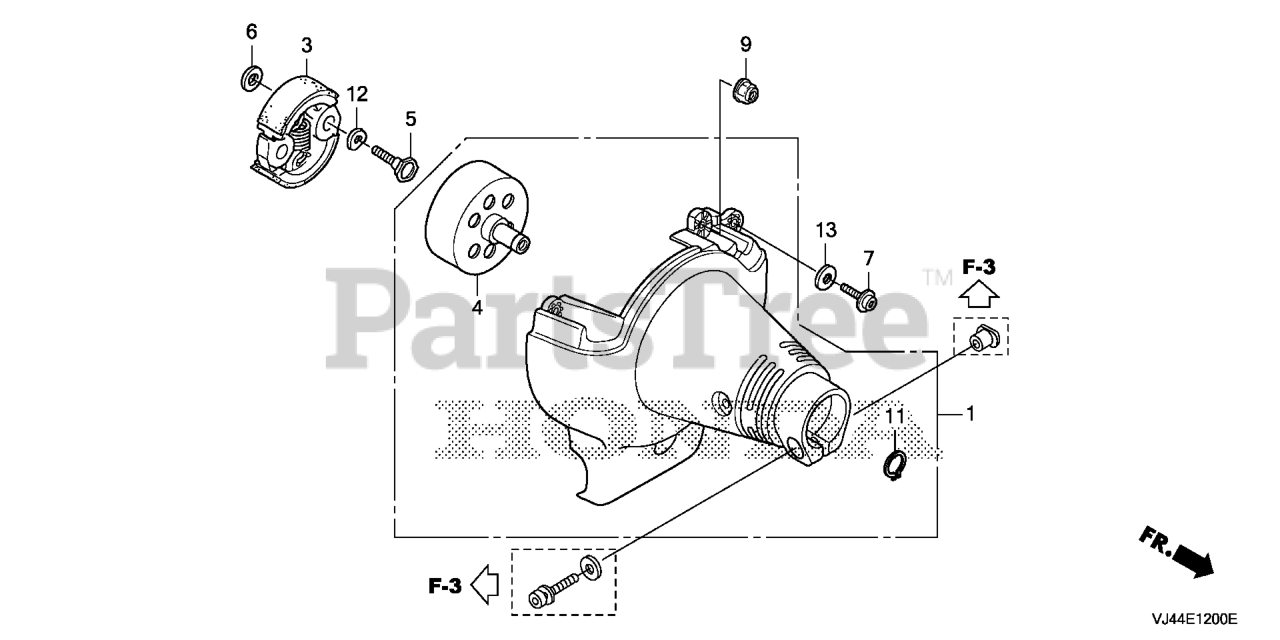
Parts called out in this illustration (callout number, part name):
1	COVER ASSY., FAN
3	CLUTCH ASSY.
4	CLUTCH OUTER
5	BOLT, CLUTCH (6MM)
6	WASHER, CLUTCH (6X15)
7	BOLT, SOCKET (5X20)
9	NUT, SPECIAL (4MM)
11	CIRCLIP (OUTER) (10MM)
12	WASHER, WAVE (8MM)
13	WASHER, PLAIN (5MM)
